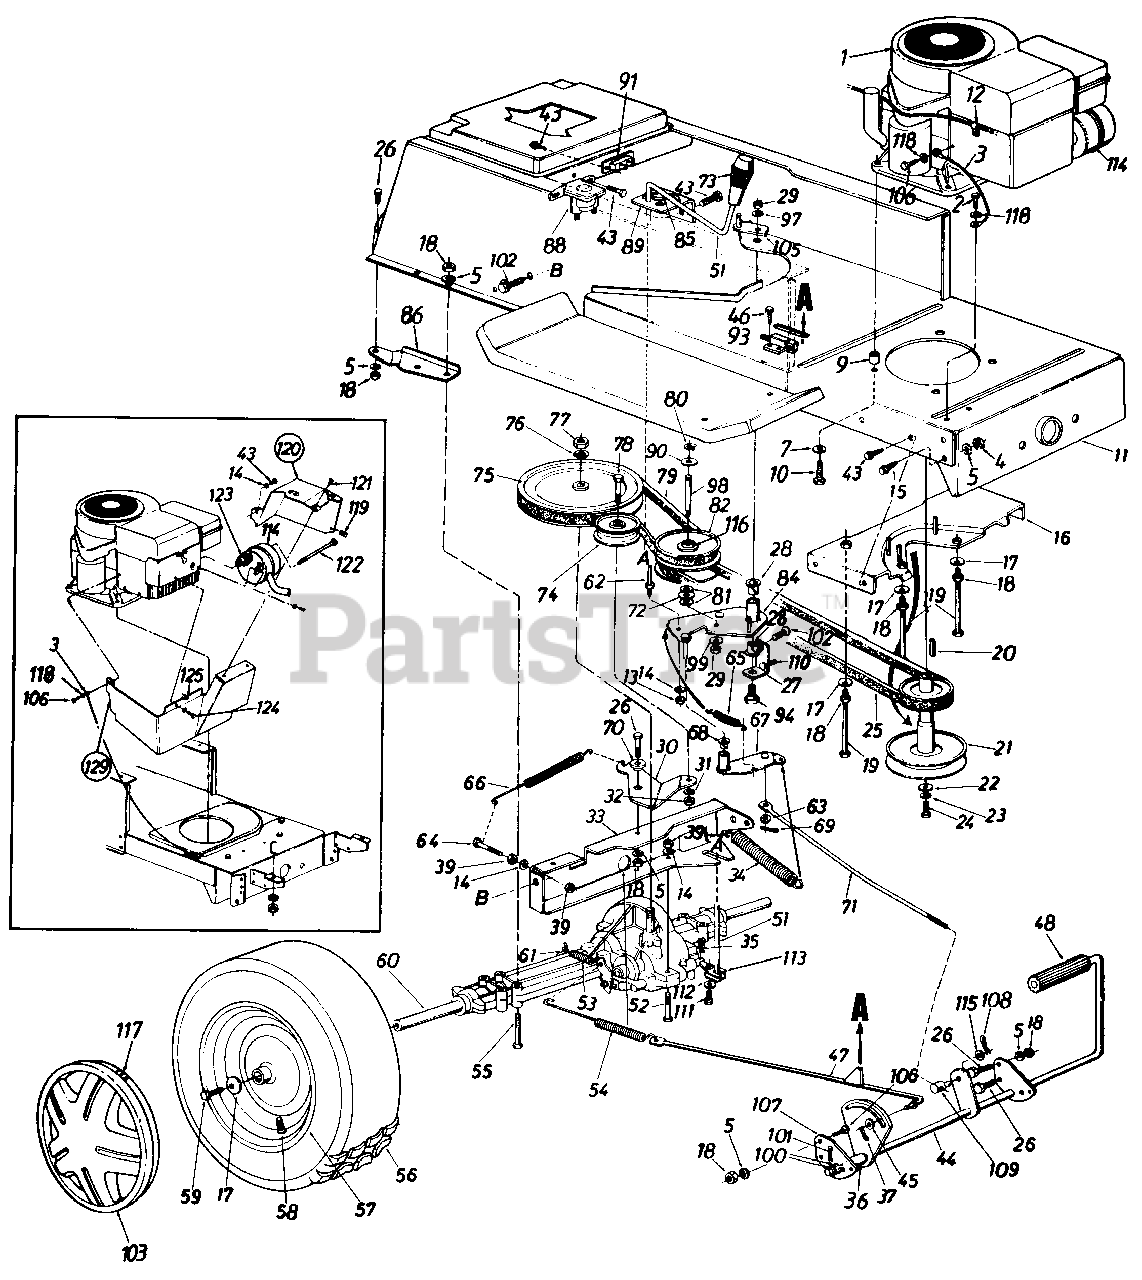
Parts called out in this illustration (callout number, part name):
1	Engine
2	Hex Wash. AB-Tap Scr. 5/16" x .75"
3	Electric Ground Wire
4	Hex Nut 5/16-24 Thd.
5	L-Wash. 5/16" l.D.
7	Fl-Wash. .406" I.D. x 1.25"
10	Hex L-Wash. Tap Scr. 3/8-16 x 1.5" Lg.
11	Lower Frame Ass'y.
13	Hex Nut 1/4-20 Thd.'
14	L-Wash. 1/4" I.D.
15	Rib Neck Bolt 5/1624 x .84" Lg.
16	Belt Guard Brkt. Ass'y.
17	Bell-Wash. .345" I.D. x .88"
18	Hex Nut 5/16-18 Thd.
19	Hex Bolt 5/16-18 x 4.0n
20	Sq. Key t/4 x 1/4" x 2.00"
21	Engine Pulley
22	Fl-Wash. 7/16" l.D. x 1.25"
23	L-Wash. 7/16" .G.
24	Hex Bolt 7/16-20 x 1.50" Lg.
25	Variable-Speed Belt
26	Hex Bolt 5/16-18 x .75" Lg.
27	Bearing Shaft Bracket Ass'y.
28	Flanged Nyliner Brg. 5/8" I.D. x .88" Lg.
29	Hex Nut 3/8-24 Thd.
31	L-Wash. 3/8" I.D.
32	Hex Nut 3/8-24 Thd.
33	Transaxle Support Brkt.
34	Ext. Spring .94" O.D. x 7.58"
35	Inter. Cott-Pin
36	Spacer.63" I.D.
37	Cotter Pin 3/32" Dia. x .75"
39	Hex Nut l/4-28 Thd.
43	Hex Wash. Hd. S-Tap Scr. 1/4-20 x .50" Lg.
44	Clutch/Brake Pedal Ass'y.
45	Fl-Wash.
46	Truss Mach. Scr. B-Tap Scr. #10 x .5" Lg.
47	Brake Rod Ass'y.
48	Foot Pad
51	Shift Lever Ass'y.
52	Hex Bolt 1/4-28 x 1.75" Lg.
53	Ext. Spring .38" O.D. x 2.5"
54	Ext. Spring .59" O.D. x 7.08"
55	Hex Bolt 5/16-18 x 2.75"
57	Wheel Rim Only
58	Air Valve
59	Hex Bolt 5/16-24 x .75" Lg.
60	Transaxle Complete
61	Brake Return Spring Anchor
62	Belt Guard Pin 1/4-20 Thd.
63	Fl-Wash. 34" l.D. x .68" O.D.
64	Hex Bolt 1/4-28 x 1.25" Lg.
65	Ext. Spring
66	Ext. Spring .62" O.D. x 6.12"
68	Flanged Bearing
69	Cotter Pin 8/32" Dia.
70	Shoulder Spacer 27" Lg.
71	Speed Control Link
72	Truss Bearing .56 Dia. x 1 .25"
73	Shift Knob
74	Fl-ldler Pulley 3 25" x .75"
75	1/2 n 'V"-Pulley
76	L-Wash. 1/2" l.D.
77	Hex Jam Nut l/2-20 Thd.
78	Hex Bolt 3/8-24 x 1.75" Lg.
79	Variable Speed Belt
80	Snap Ring 56" Dia.
82	Variable Speed Pulley Ass'y. 5" O.D.
90	Teflon Washer .565" I.D.
91	Circuit Breaker
93	Safety Switch
94	Shld. Bolt 3/8-24 x 3.12" Lg.
97	Bell-Wash. 38" l.D. x .88"
98	Shaft 56" Dia. x 3.875" Lg.
99	Bell-Wash. .39" I.D. x 1.12"
100	Fl-Wash. .64" I.D. x .94"
101	Cotter Pin 3/32" Dia. x 1.0"
102	Hex Wash. Hd. Scr. 5/16-18 x 62" Lg.
103	Hub Cap
105	Belt Guard
106	Truss Mach. Scr. 5/16-18 x .75" Lg.
107	Pedal Bracket
108	Cotter Pin 3/32" Dia. x .75"
109	Ferrule
110	Hex Bolt 5/16-18 x 1.0" Lg.- (Gr. 5)
111	Hex Bolt 1/4-28 x .50" Lg.
112	Bell-Wash. .265" I.D. x .75"
113	Shift Lever Link Ass'y.
114	Muffler
115	Fl-Wash. .385" I.D. x .62"
116	Needle Brgs.
117	Spring Clip
118	External L-Wash. 5/16" I.D.
119	Speed Nut #10-24
120	Muffler Heat Shield-L.H.
121	Hex Wash. Tap Scr. #10 x .50" Lg.
122	Shld Scr. 7/16 Dia. x 3-5/8"
123	Gasket
125	L-Wash.
129	Muffler Heat Shield-Front
